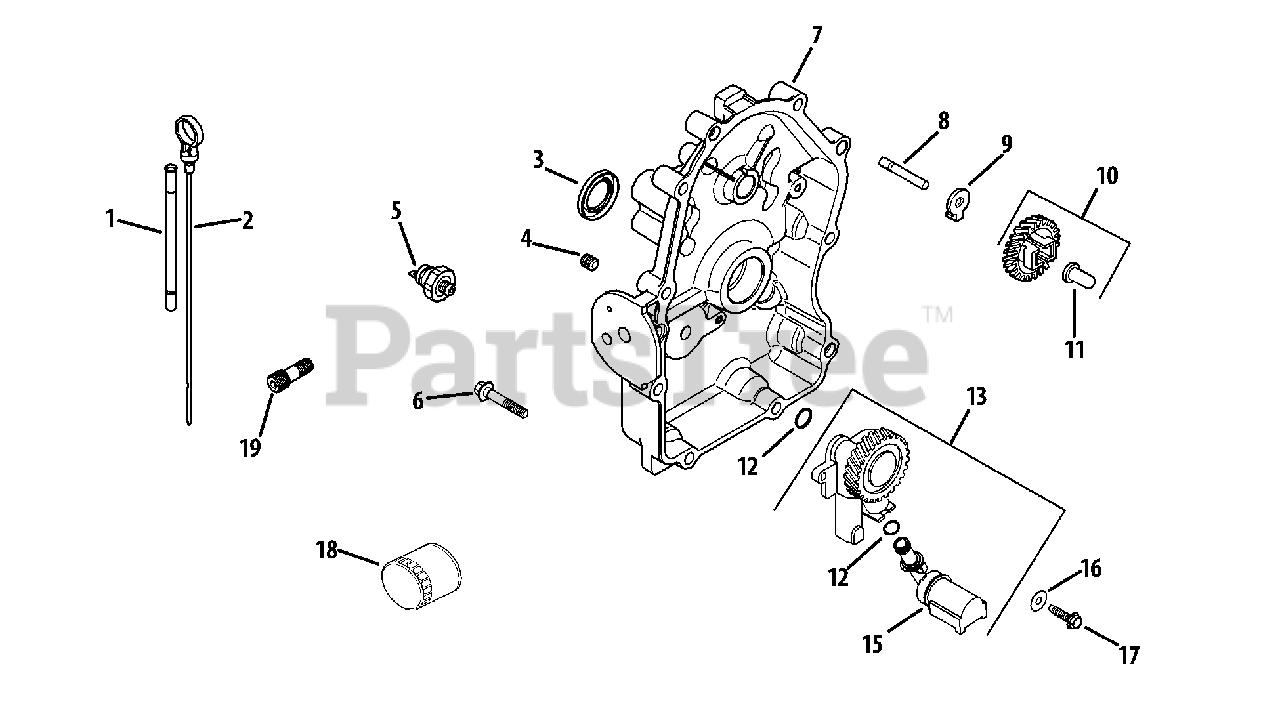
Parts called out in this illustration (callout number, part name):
1	Dipstick/Dipstick Tubes Kit
4	Countersink Pipe Plug, 1/8
5	Oil Pressure Switch
6	Flange Screw, M8 x 1.25 x 45
7	Closure Plate Assembly
8	Governor Gear Shaft
10	Governor Gear Kit w/ Pin
11	Governor Regulating Pin
13	Oil Pump Assembly Kit
14	Oil Pick-Up O-Ring
16	Flat Washer, 1/4 x 5/8
17	Thread Forming Screw
19	Oil Filter Nipple
